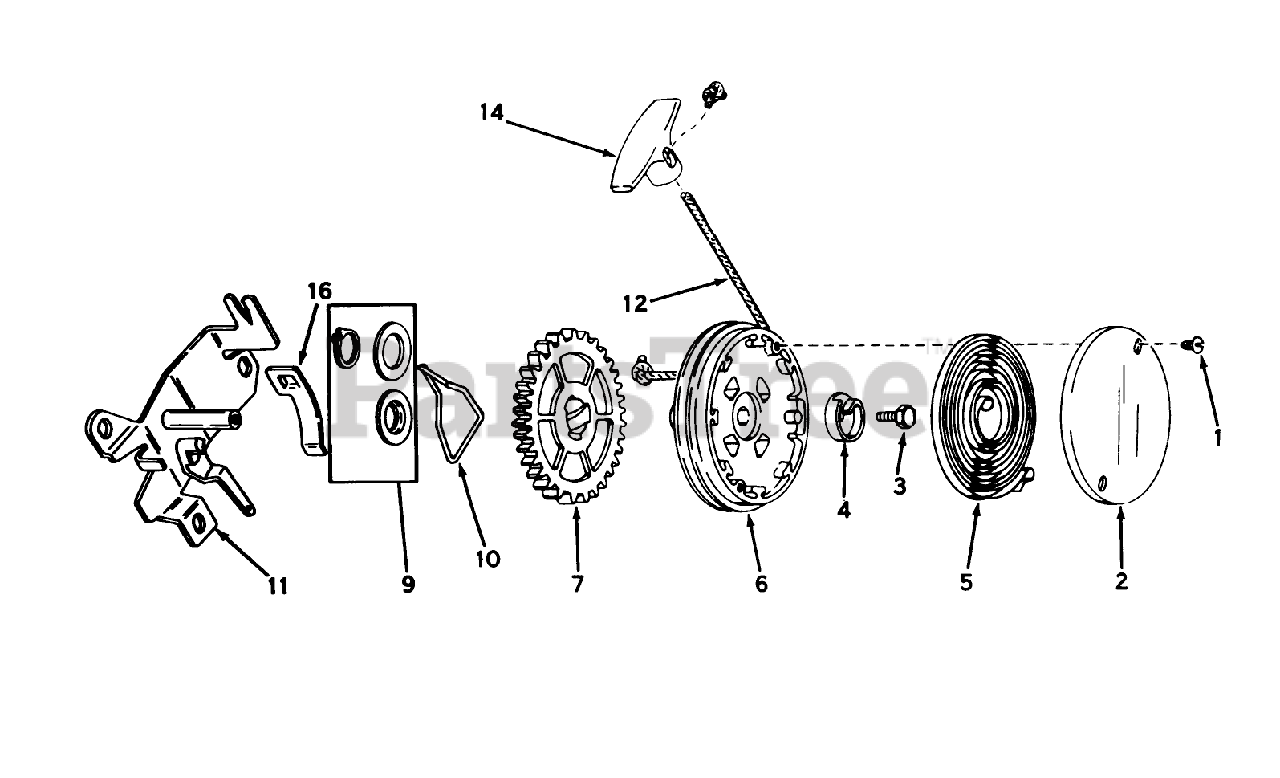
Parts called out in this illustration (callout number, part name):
1	Screw
2	Cover, Spring
3	Screw, Hex Washer Head
4	Hub Spring
5	Spring, Rewind
6	Pulley Assy. (Incl. No. 9)
9	Kit, Thrust Wash. Snap Rg.
10	Brake
11	Bracket Assy., Mounting
12	Rope-Starter
14	Handle-Starter
16	Clip Rope
